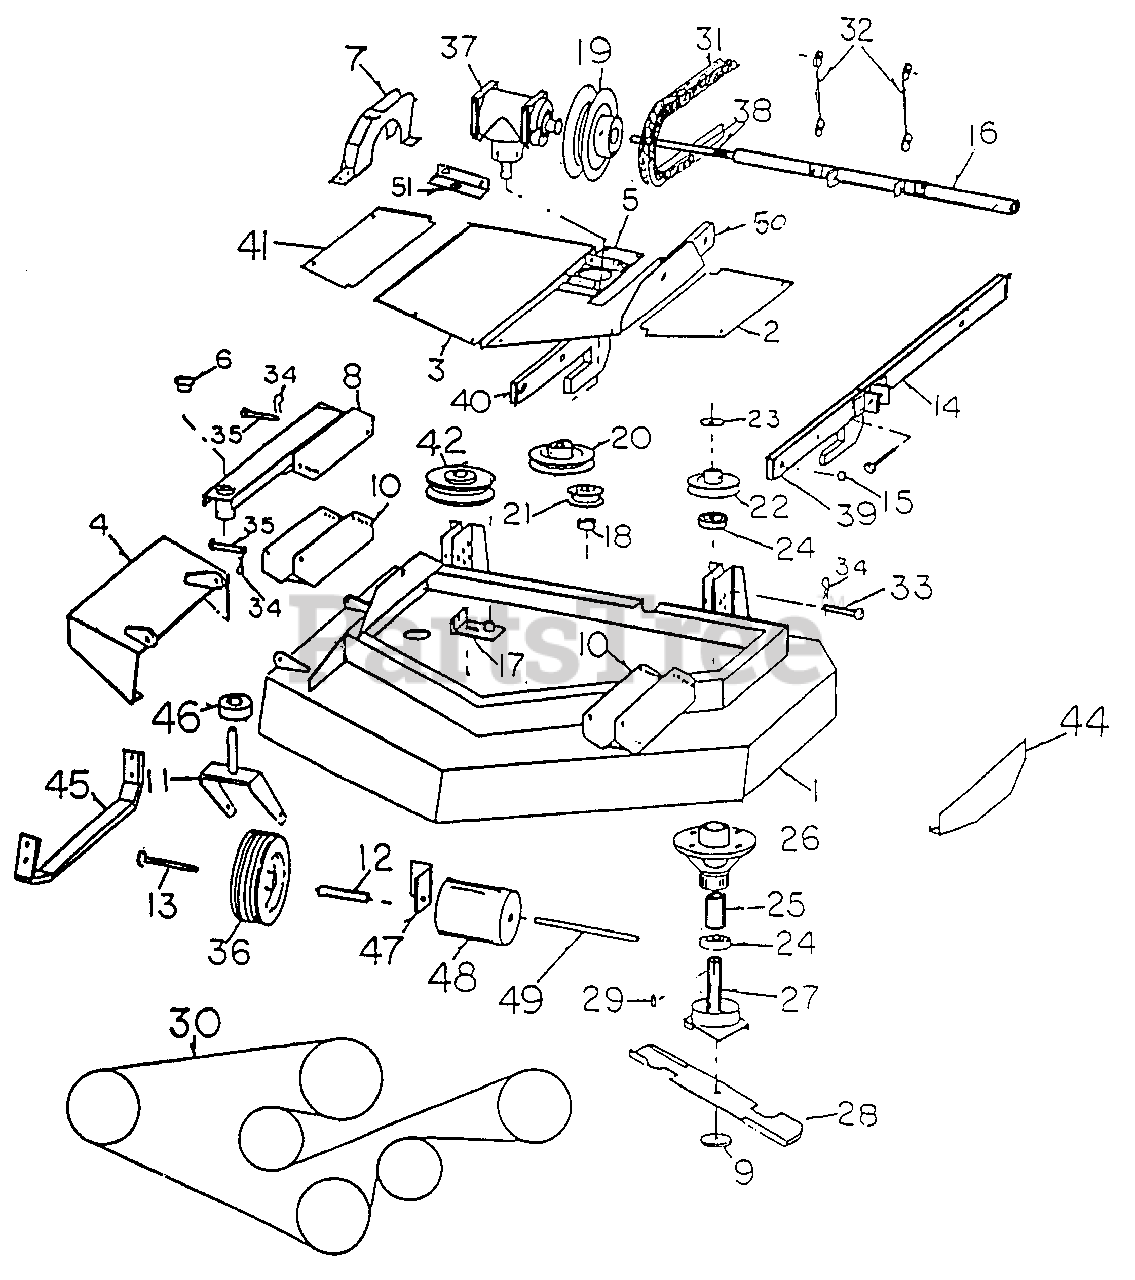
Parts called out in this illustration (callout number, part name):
1	MOWER DECK
5	GEAR BOX MOUNT
6	GAUGE WHEEL BEARINGS
8	GACE WHEEL MOUNT
10	BRACKET GAGE WHEEL MOUNT
11	FORK GAGE WHEEL
12	AXLE
13	AXLE BOLT
14	LH. DECK LIFT ARM BACK ADJUSTABLE
15	BUSHING, DECK LIFT ARM
17	BELT TIGHTENER
18	SPACER IDLER
19	PULLEY GEAR BOX
20	PULLEY GEAR BOX
21	5-IDLER
22	PULLEY SPINDLE
23	WASHER SPINDLE
24	BEARING SPINDLE
25	SPACER SPINDLE
26	HOUSING SPINDLE
27	SHAFT SPINDLE
29	KEY SPINDLE
35	PINS, CAGE WHEEL
38	CROSS BAR PIN
39	L.H. DECK LIFT ARM FRONT ADJUSTABLE L.H.
40	R.H. DECK LIET ARM FRONT ADJUSTABLE R.H.
41	COVER, RICHT HAND SIDE
42	PULLEY, IDLER LARGE
44	SHOE LEET HAND SIDE
45	SHOE RICHT HAND SIDE
47	ROLLAR BRACKET
50	R.H. DECK LIFT ARM BACK ADJUSTABLE
51	GEAR BOX MOUNT ANGLE
